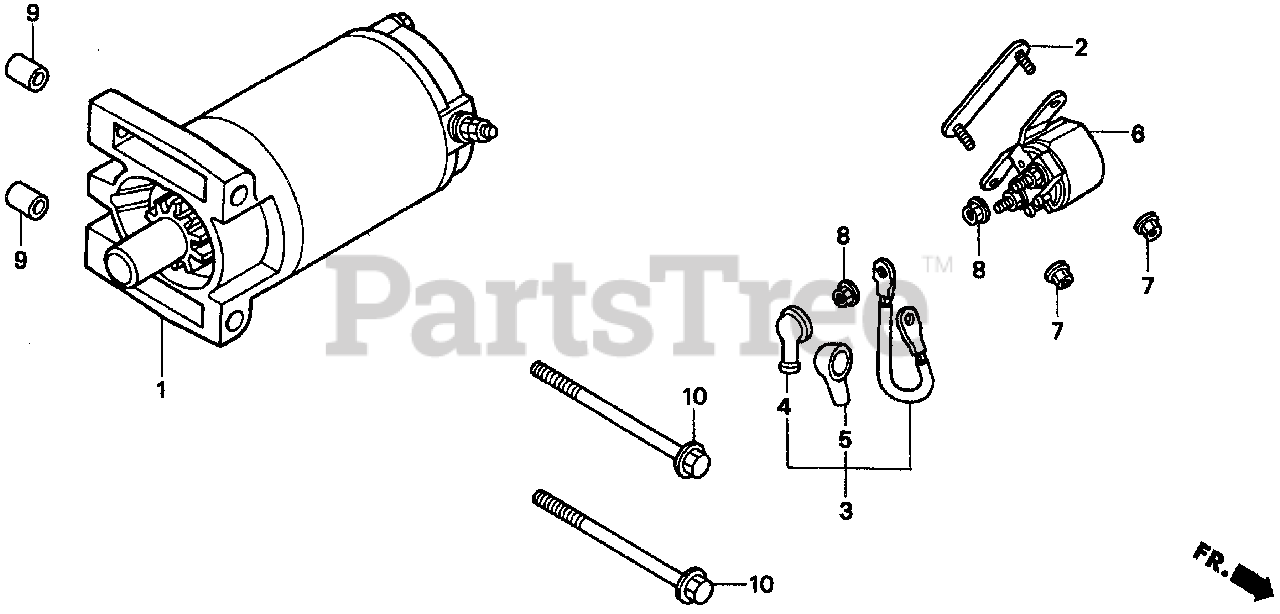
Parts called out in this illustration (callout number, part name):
1	STARTER MOTOR ASSY. (NOT AVAILABLE)
2	BRACKET, STARTER MAGNETIC SETTING
3	WIRE, MAGNETIC SWITCH (NOT AVAILABLE)
4	COVER A, MAGNETIC SWITCH
5	COVER, STARTER MOTOR TERMINAL
6	SWITCH ASSY., STARTER MAGNETIC
7	NUT, FLANGE (6MM)
8	NUT-WASHER (6MM)
9	PIN, DOWEL (10X12)
10	BOLT, FLANGE (8X110)
